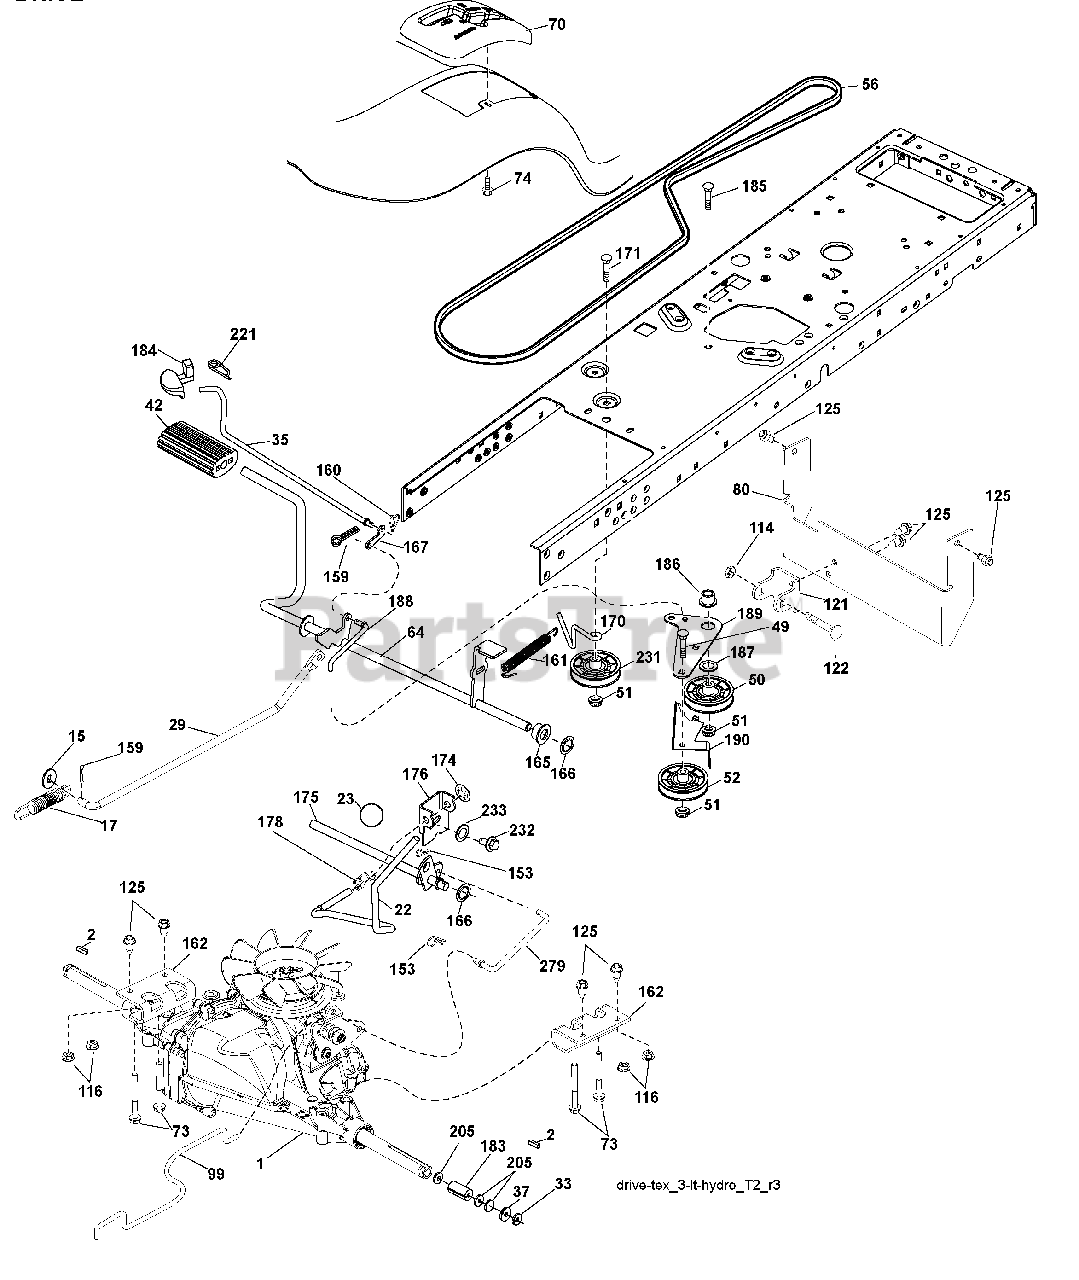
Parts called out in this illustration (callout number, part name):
1	Transaxle, Hydro Gear T2 (See Transaxle Breakdown)
2	Key Square
15	Washer 13/32 x 13/16 x 16 Ga.
17	Spring, Brake
22	Rod Shift
23	Knob
29	Rod, Brake
33	Ring E
35	Rod, Brake, Park
37	Washer 25/32 x 1-1/4 x 16 Ga.
42	Cover, Foot Pedal
49	Bolt
50	Pulley Idler Flat
51	Lock Nut 3/8-16
52	Idler V-Groove 910" Offset
56	V-Belt, Drive
64	Shaft Asm. Pedal Brake Control
70	Console
73	Bolt Hex 5/16-18 Gr. 5
74	Screw 1/4 x 1/2
80	Strap Torque
99	Rod Spring Bypass
114	Nut Lock 5/16-18 UNC
116	Nut Lock Hex Flange 5/16-18
121	Bracket Strap Torque
122	Bolt 5/16-18 x 2.50
125	Screw 5/16-18 x 3/4
153	Retainer Spring 1"
159	Pin Cotter 1/8 x 3/4
160	Retainer Clip
161	Spring, Return, Clutch
162	Adapter, Transaxle T2
165	Bushing
166	Nut Push .625
167	Latch Brake Parking
170	Keeper Belt Centerspan
171	Bolt
174	Nut Push
175	Shaft Asm Shift
176	Arm Clevis Rod Shift
178	Spring Shift
183	Spacer Axle
184	Handle Parking Brake
185	Bolt
186	Spacer Retainer
187	Washer
188	Link Clutch Ground Drive
189	Bellcrank Ground Drive
190	Keeper Bellcrank Ground Drive
205	Washer 25/32 x 1-5/8 x 16 Ga.
231	Idler V-Groove 1.688" Offset
232	Bolt 7/16-14 x 1 Gr 5
233	Washer Serrated
279	Link Shift
